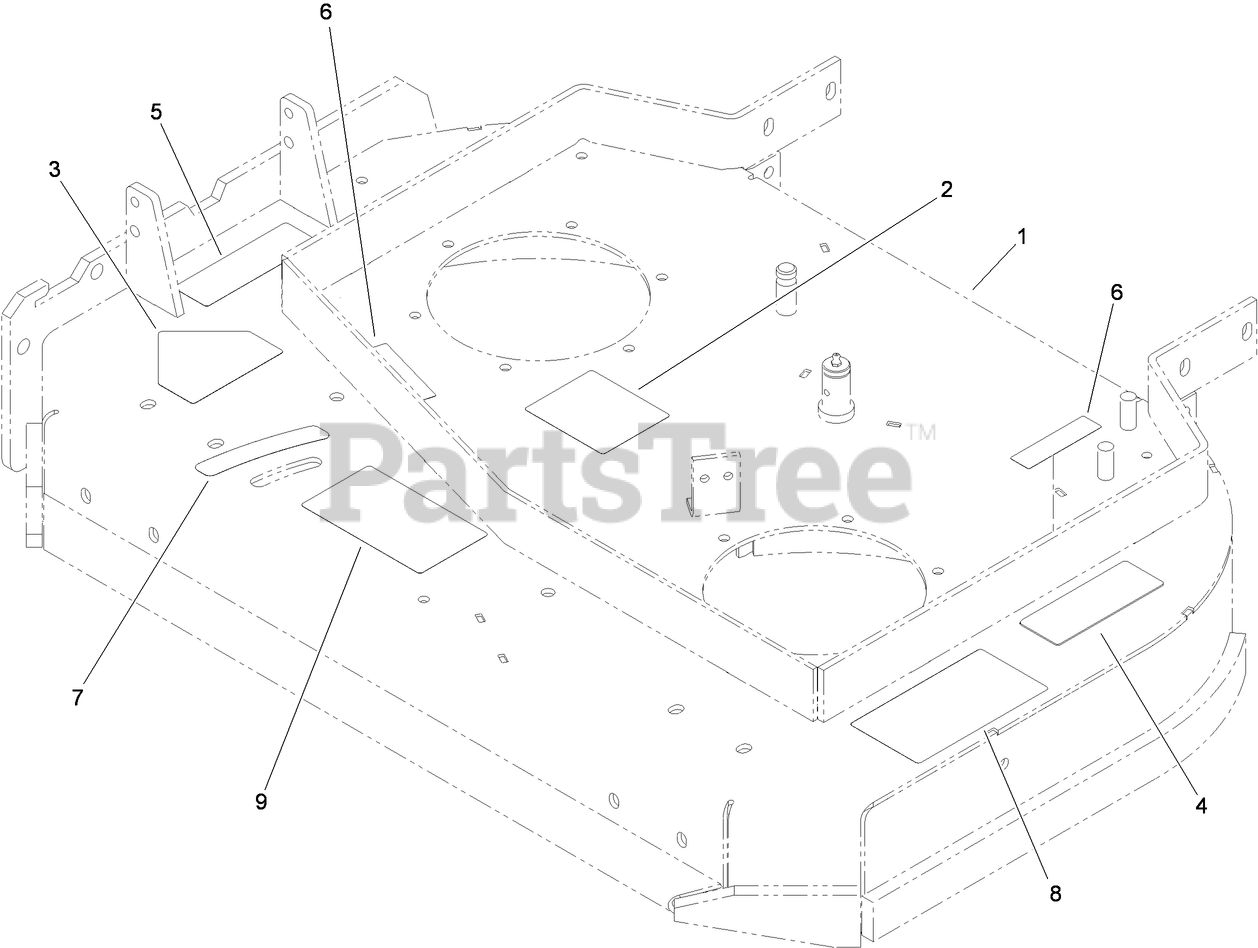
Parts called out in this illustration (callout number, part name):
1	36 INCH DECK ASM
2	DECAL-ROUTING, BELT
3	DECAL-DANGER
4	DECAL-TORQUE, BOLT
5	DECAL-WARNING
6	DECAL-COVER, MISSING
7	DECAL-SETTING, BAFFLE
8	DECAL-DANGER, THROWN OBJECT
9	DECAL-ADJUSTMENT, BAFFLE
